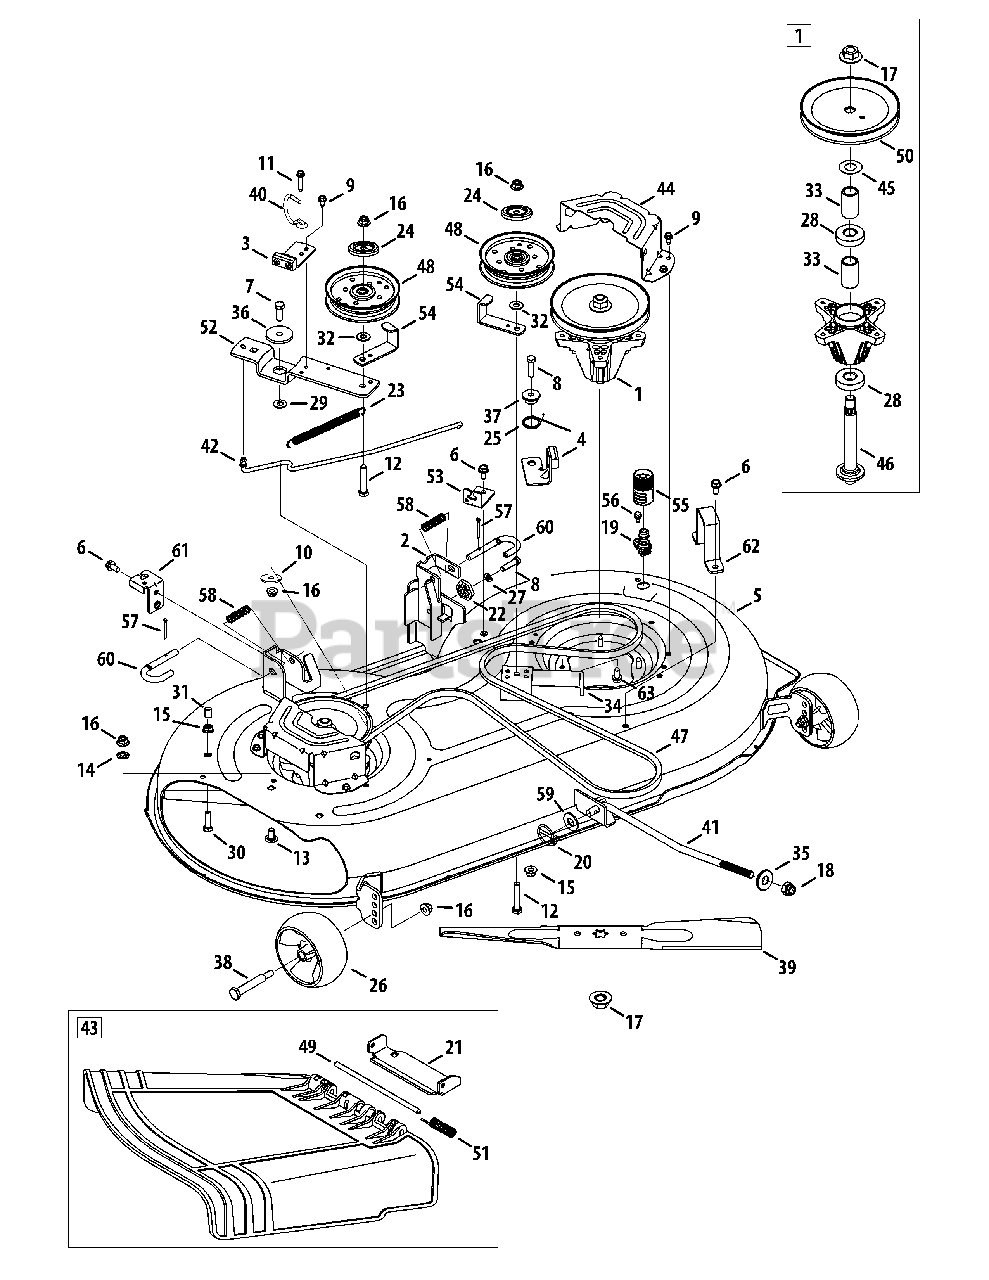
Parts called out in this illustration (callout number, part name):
1	Pulley Spindle Ass’y 6.3 dia.
2	Deck Hanger Bracket Ass’y LH
3	Deck Brake Assembly
4	Deck Brake Assembly
5	Deck Assembly, 42" w/o wheel
6	S-Tapp Scr 5/16-18 x .75
7	Hex Screw, 3/8-16, 1.25, Gr5, Std
8	Hex Wash Tap Scr 5/16-18 x 1.25
9	Hex Wash S-Tapp Scr 1/4-20 x .50
10	Flat Washer .406 x 1.5 x .105
11	Hex Bolt 1/4-20 x .75
12	Hex. Hd. Cap Scr. 3/8-16 x 2.0 Gr. 5
13	Carriage Bolt 3/8-16 x .75 Gr. 1
14	Push Nut, 3/8
15	Hex Flange Locknut 5/16-18 Gr. F, Nylon
16	Hex Flange Locknut 3/8-16 Gr. F, Nylon
17	Hex Flange Locknut 5/8-18
18	Hex Locknut 1/2-13
19	Deck Water Nozzle
20	Lynch Pin
21	Chute Bracket
22	Deck Gear Adjuster
23	Extension Spring .62 dia. x 6.12 Lg.
24	Pulley Cap
25	Torsion Spring .992 ID x 1.17 OD
26	Deck Wheel 5.0 Dia.
27	L-Wash 5/16 ID
28	Ball Bearing .787 ID x 1.85 OD x .551
29	Flat Washer .385 x 1.0 x .030
30	Hex Cap Screw 5/16-18 x 1.0
31	Cap .290 x .50
32	Flat Washer .385 ID x .870 OD x .092
33	Spacer .792 x 1.060 x 1.860
34	Deck Support Stationary Idler Brkt.
35	Cupped Washer .63 x 1.25 x .18
36	Shoulder Spacer .8540 x .200
37	Shoulder Spacer .50 x .145
38	Shoul der Bolt .496 x 2.5, 3/8-16
39	Blade, 21.23", 2-in-1
40	Belt Keeper Rod
41	Front Lift Deck Rod
42	Brake Control Rod
43	Side Discharge Chute Assembly
44	Deck Belt Cover, 42
45	Flat Washer .760 ID x 1.5 OD
46	Spindle Shaft 6.11" Lg.
47	V-Belt
48	Idler Pulley w/Flange 4.25 Dia.
49	Hinge Pin .3125 diam. x 7.96" Lg.
50	Deck Pulley 6.3 dia.
51	Torsion Spring .44 ID x 2.0
52	Idler Pivot Bracket
53	Deck Cable Engagement Bracket
54	Belt Guard Pulley Bracket
55	Water Nozzle Adapter
56	Shoulder Screw 1/4-20 x 0.50
57	Cotter Pin 1/8 x 1.25
58	Compression Spring .535 OD x 1.751" Lg.
59	Flat Washer .531 ID x 1.25 OD x .100
60	Deck Release Pin
61	Cable Bracket Deck Engage
62	Deck Lift Pivot Cup
63	Hex. TT Screw 5/16-18 x .75
